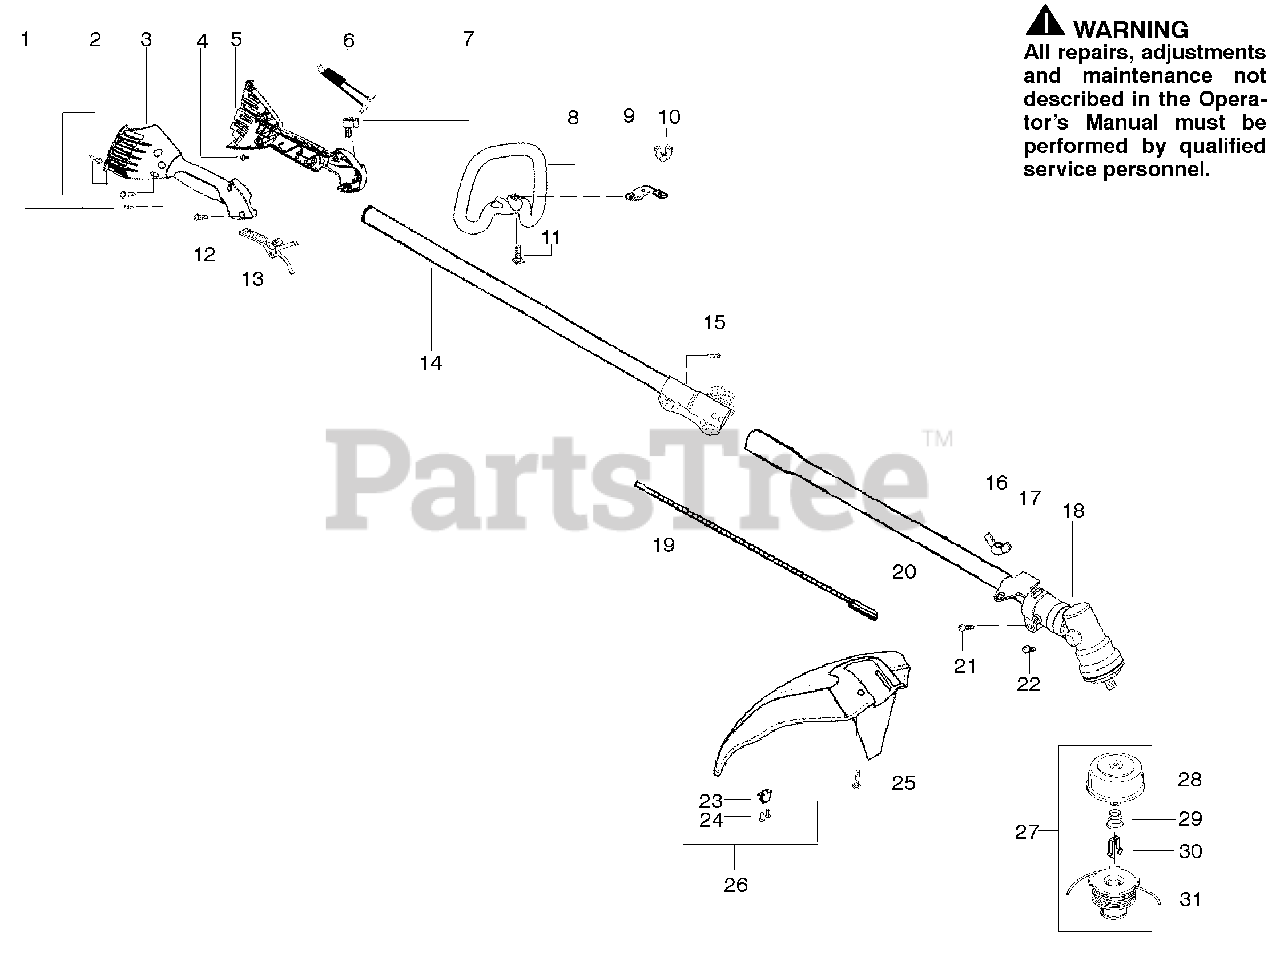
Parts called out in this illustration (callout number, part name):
1	Screw-alignment
3	Hsg.-Throttle right
4	Screw-Cable Retention
5	Hsg.-Left throttle
8	Handle-Assist
10	Wingnut
13	Lever-Throttle
14	Assy-Upper Shaft
16	Wingnut
17	Bracket-Shield
19	Shaft-Flex (lower)
20	Assy-Lower Shaft
26	Kit-Shield Assy.
27	Accy-Cutting Head
28	ssy-Hub/Arbor
29	Spring-Return
30	Retainer-Spool
31	Accy-Wound Spool
31	Operator Manual
31	Decal-Shaft Warning
31	Decal-Upper Shaft
31	Decal-Start Inst.
